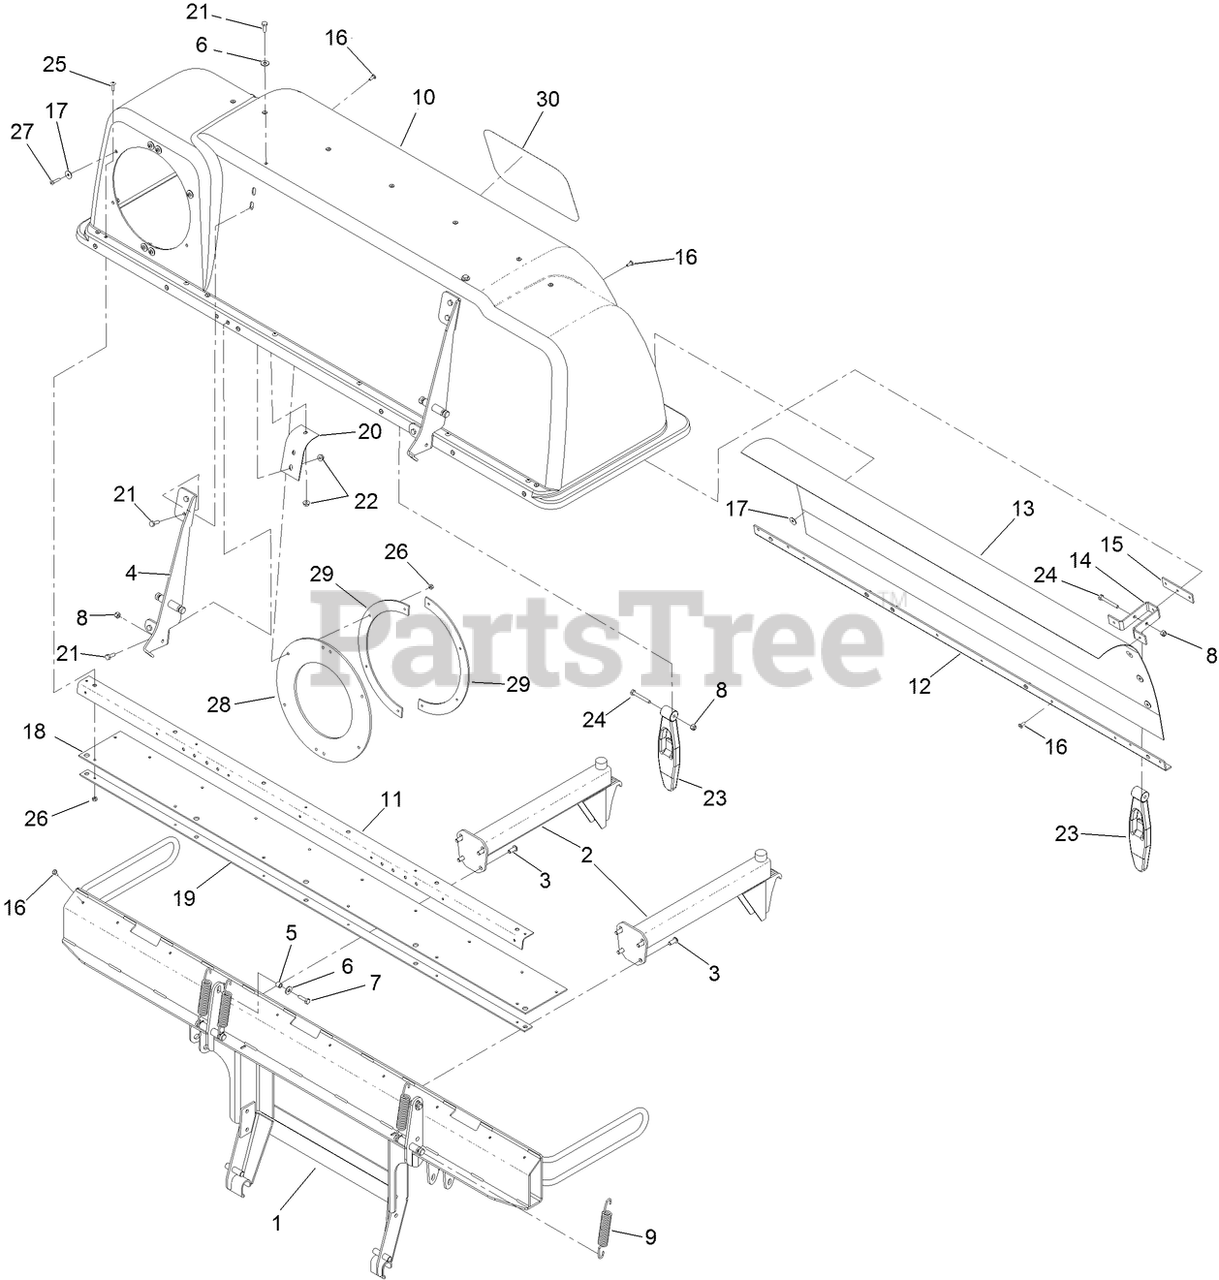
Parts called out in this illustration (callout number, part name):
1	FRAME-3-BAG
2	BAG SUPPORT ASM
3	SCREW-HSBH
5	SPACER
6	WASHER-FLAT
7	SCREW-HH
8	NUT-LOCK, NI
9	SPRING-EXTENSION
10	HOOD-BAGGER, TRIPLE
11	STIFFENER-BAGGER, TOP
12	SUPPORT-SCREEN
13	SCREEN-BAGGER
14	BRACKET-MOUNT
15	PLATE-LATCH, REINFORCEMENT
16	RIVET-BLIND
17	WASHER-FLAT
18	SEAL-HINGE
19	PLATE-BACKING
20	REINFORCEMENT-HOOD, BAGGER
21	SCREW-HH
22	NUT-HF
24	SCREW-HH
25	SCREW-HEAD, TRUSS
26	NUT-LOCK, NI
27	SCREW-PPH
28	SEAL-TUBE
29	CLAMP-SEAL
30	DECAL
